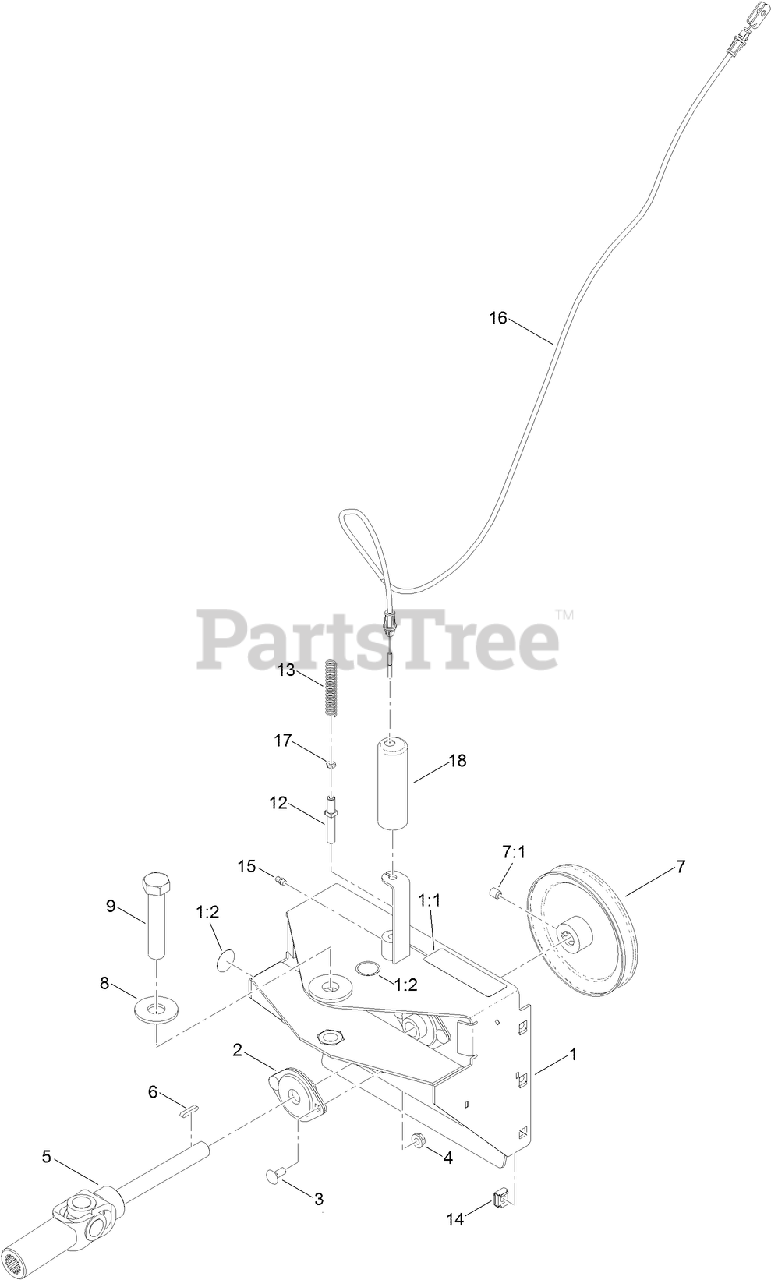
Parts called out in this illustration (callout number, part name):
1	BROOM MOUNTING FRAME ASM
1:1	DECAL-MISSING, COVER
1:2	DECAL-GREASE
2	BEARING-SHAFT
3	BOLT-CARR
4	NUT-HF
5	SHAFT-DRIVE
6	KEY-ROUND END
7	PULLEY-IMPELLER
7:1	SETSCREW
8	WASHER-FLAT
9	SCREW-HH
12	PIN-SWING
13	SPRING-COMPRESSION
14	NUT-RETAINER
15	FITTING-GREASE
16	CABLE-ANGLE, BROOM
17	NUT-HEX
